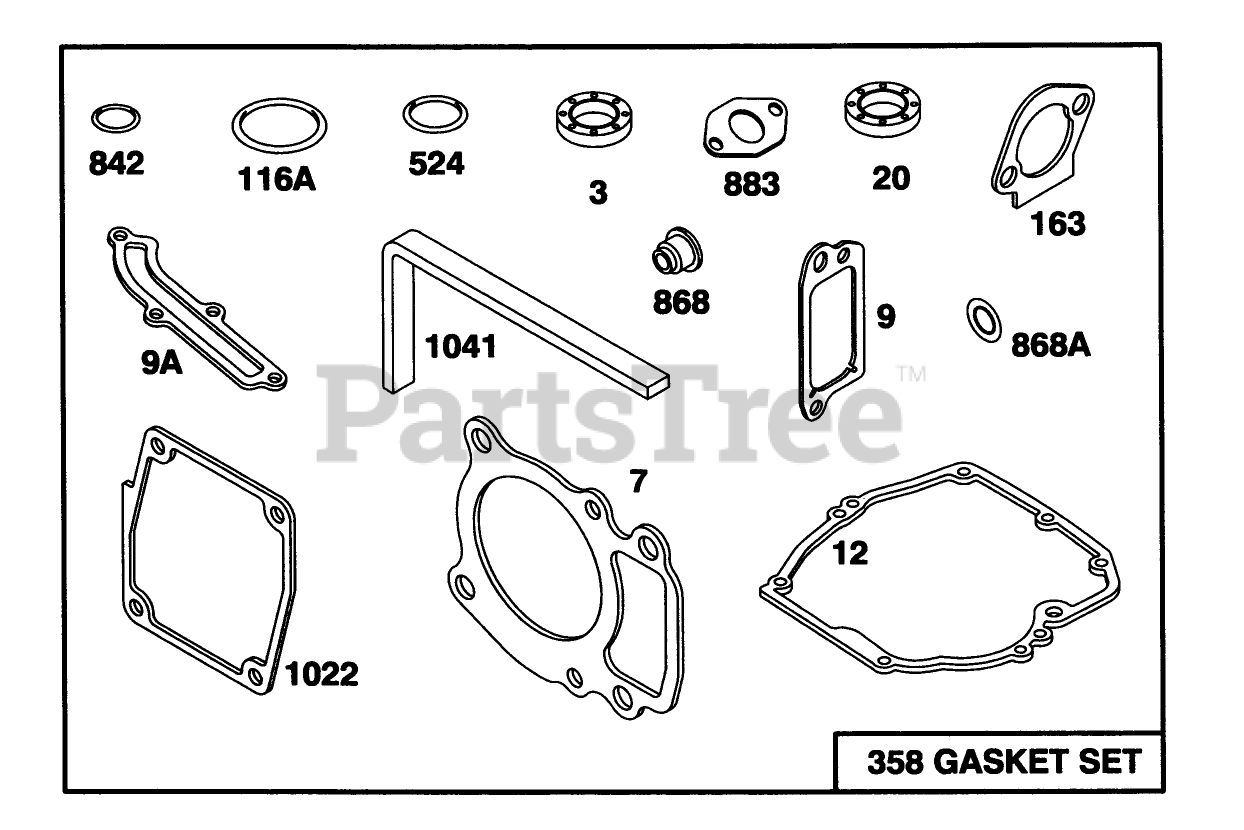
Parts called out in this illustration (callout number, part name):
7	CYLINDER HEAD GASKET
12	ENGINE BASE GASKET
20	SEAL-OIL
116A	O RING SEAL
163	AIR CLEANER GASKET
358	GASKET SET
524	O-RING
842	O-RING
1022	ROCKER COVER GASKET
